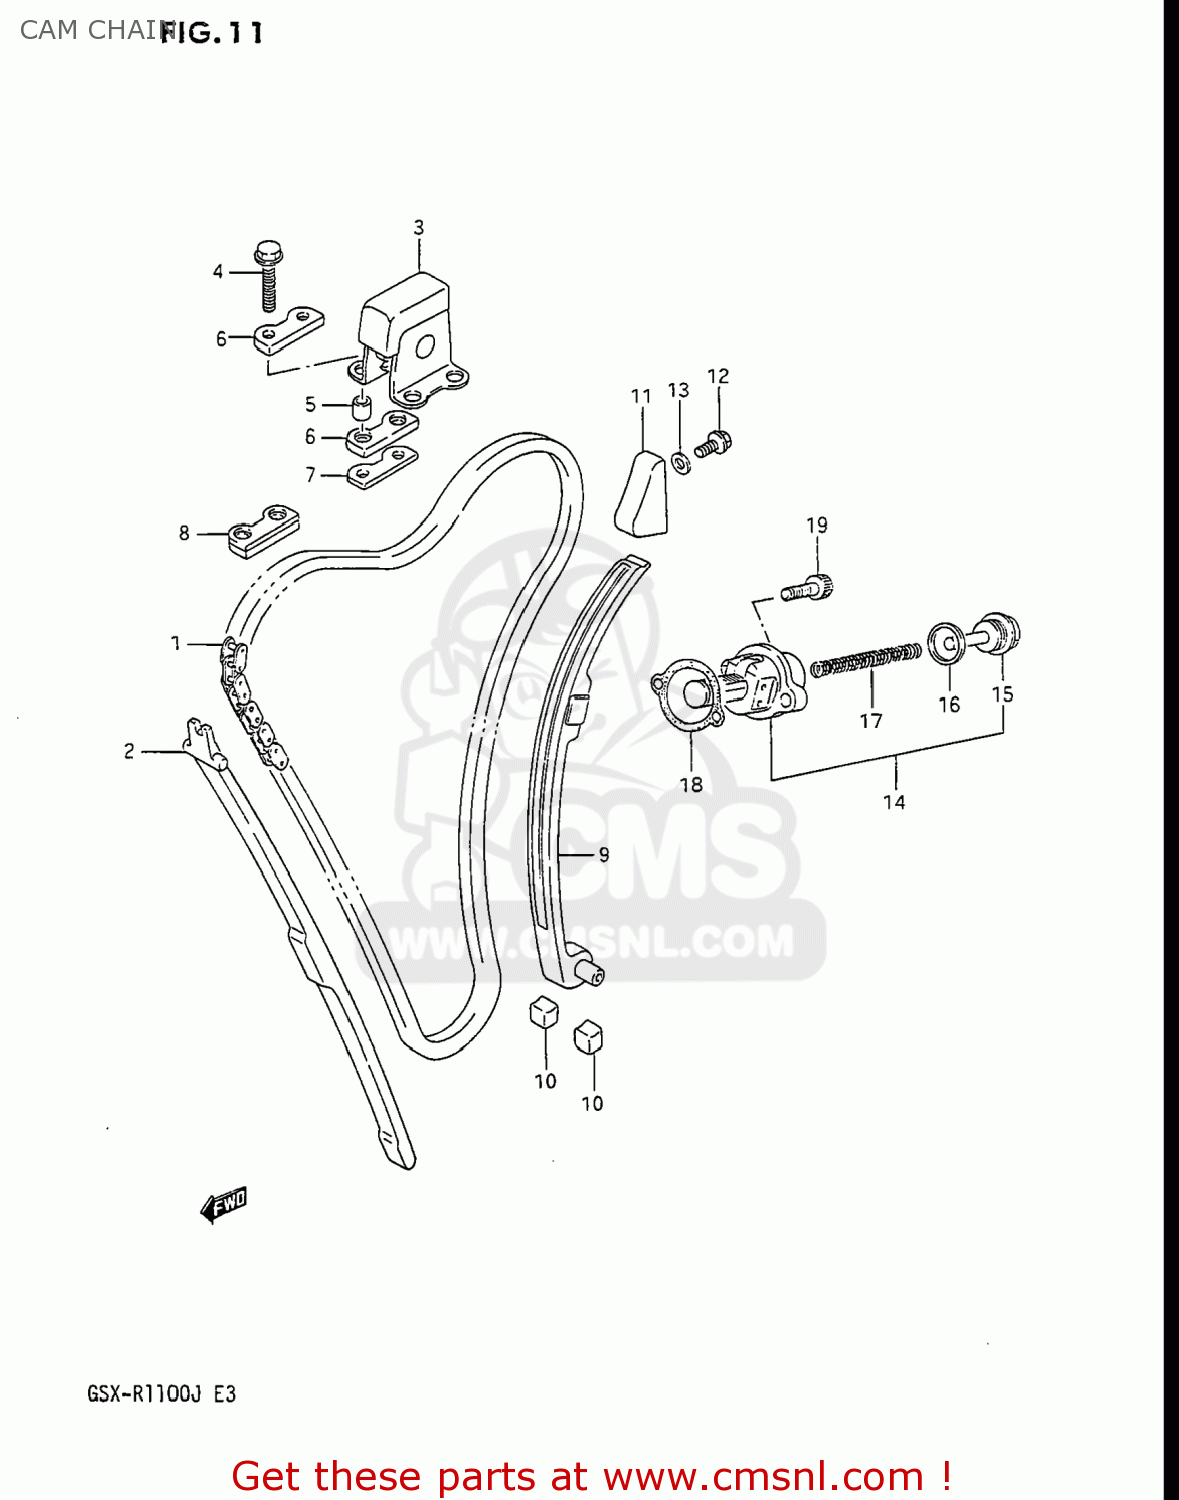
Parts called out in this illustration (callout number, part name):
1	CHAIN,CAMSHAFT DRIVE
2	GUIDE,CAM CHAIN NO.1
3	IDLER,CAM CHAIN
4	BOLT
5	SPACER (6,8X10X9.4)
6	GUIDE,CAM CHAIN
7	PLATE,CAM CHAIN IDLER
8	GUIDE,CAM CHAIN
9	TENSIONER,CAM CHAIN
10	CUSHION,CAM CHAIN TENSIONER
11	GUIDE,CAM CHAIN NO.2
12	BOLT
13	GASKET(5.8X13X1.2) (NAS)
14	ADJUSTER ASSEMBLY,TENSIONER
15	PLUG
16	GASKET (NAS)
17	SPRING
18	GASKET,TENSIONER ADJUSTER (NAS)
19	BOLT
